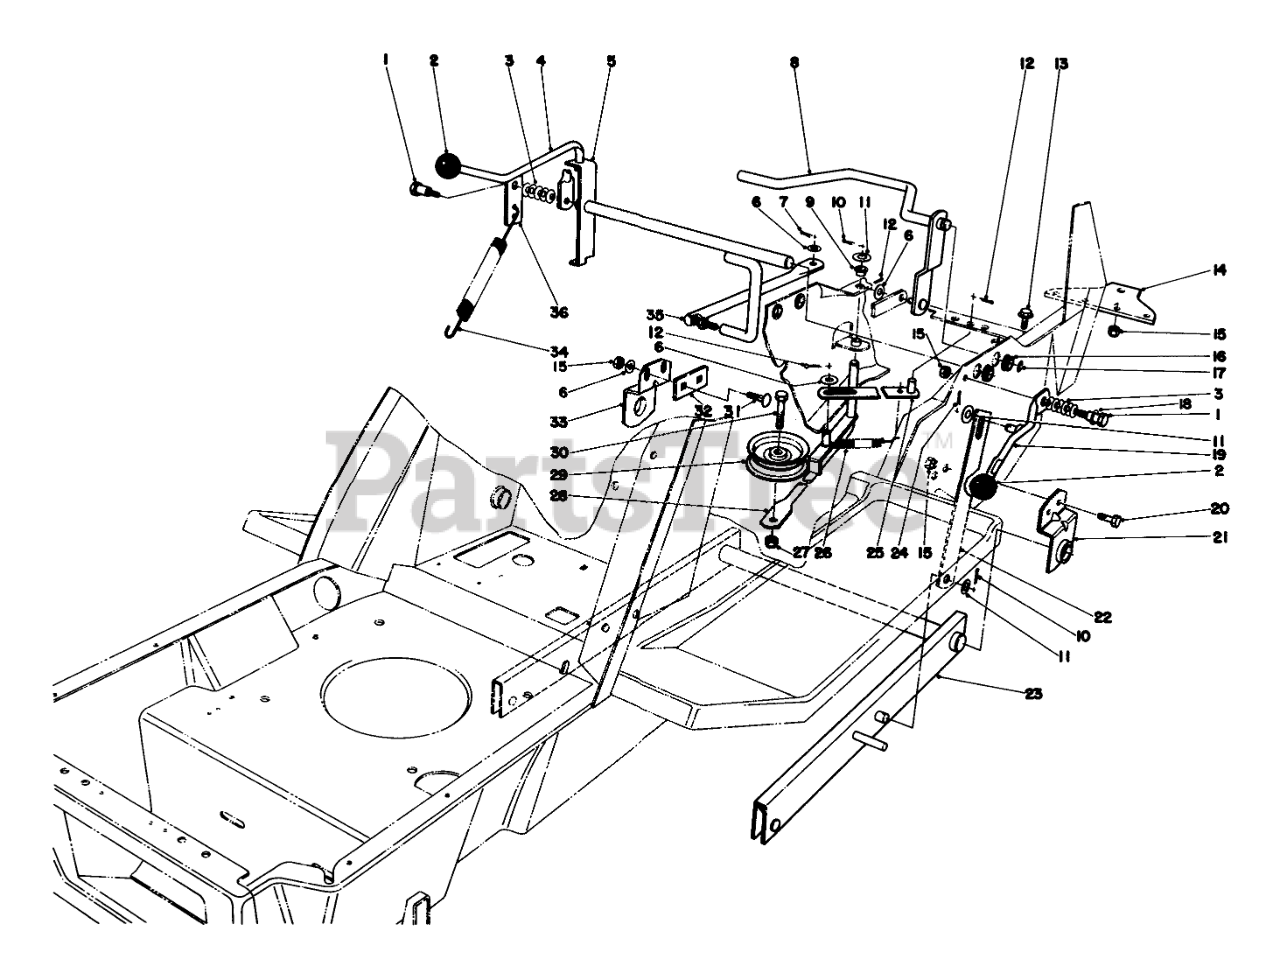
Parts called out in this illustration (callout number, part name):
1	BOLT-SHOULDER
3	WASHER-BELLEVILLE
4	SHIFT LEVER BO
5	Shim Lever
6	WASHER-PLAIN
7	PIN-COTTER
8	CLUTCH ACTUATOR WA B
9	BUSHING-NYLINER
10	PIN-COTTER
11	WASHER-FLAT
12	PIN-COTTER
13	SCREW-HHF
14	HITCH PLATE R
15	NUT-LOCK, NI
16	Nyliner
17	E-RING
18	WASHER-FLAT
19	HOC HANDLE WA B
20	SCREW-HH
21	LH PIVOT BAR RET B
22	H.O.C. STRAP B
22	HOC LINK B
23	Bar-Pivot
24	PIN-COTTER
25	SPRING RET WA B
26	DECK TENSION SPRNG O
27	NUT-LOCK, CONE
28	IDLER ARM WA BO
29	IDLER PULLEY
30	SCREW-HH
31	BOLT-CARR
32	SPACER
33	RH PIVOT BAR RET B
34	TRACTION SPRING
35	SHIFT ARM BO
36	BRKT-COBALANCE SPRING
